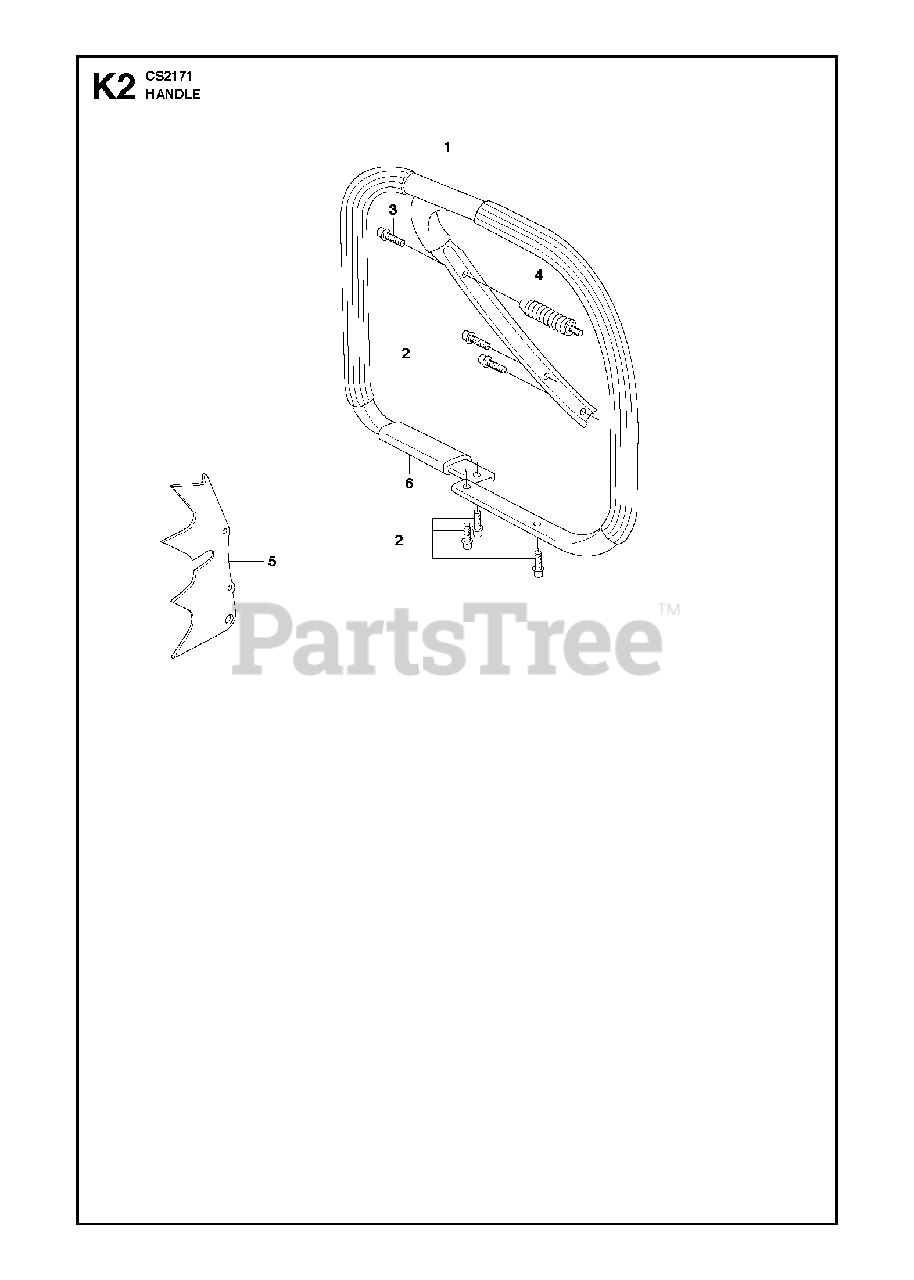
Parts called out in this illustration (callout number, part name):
1	FRONT HANDLE
2	SCREW
3	SCREW
4	ANTIVIBE MOUNT
5	FELLING DOG
